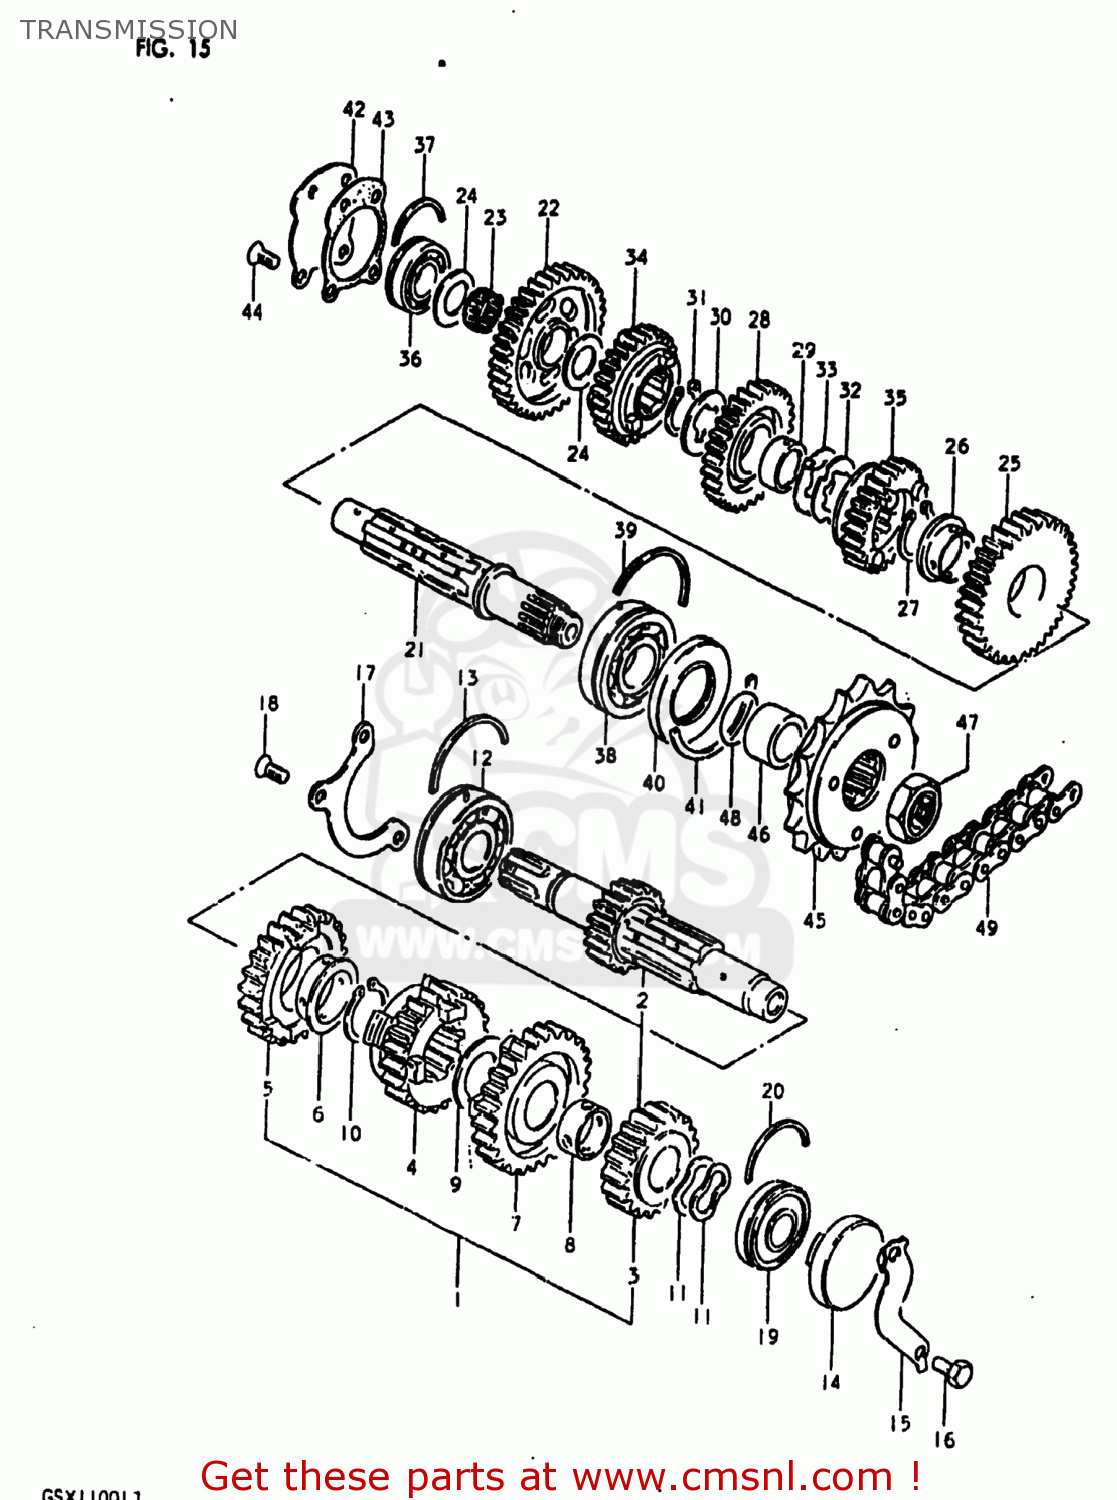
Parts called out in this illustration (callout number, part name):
1	SHAFT,COUNTER
2	SHAFT,COUNTER
3	GEAR,SECOND DRIVE
4	GEAR,3RD DRIVE(NT:21)
5	GEAR,FOURTH DRIVE
6	BUSH(28X32X2)
7	GEAR,FIFTH DRIVE
8	BUSHING
9	WASHER
10	CIRCLIP
11	WASHER
12	BEARING(25X62X17)
13	C-RING
14	PLUG
15	RETAINER,CL PUSH ROD OIL SEAL
16	BOLT
17	RETAINER,CNTR SHAFT BEARING
18	SCREW
19	BEARING(20X47X14)
20	C RING
21	SHAFT,DRIVE
22	GEAR,FIRST DRIVEN (NT:35)
23	BEARING(20X24X10).8
24	WASHER
25	GEAR,SECOND DRIVEN
26	BUSH(28X32X2)
27	CIRCLIP
28	GEAR,THIRD DRIVEN
29	BUSH,3RD DRIVEN GEAR
30	WASHER,LOCK
31	CIRCLIP
32	WASHER,LOCK
33	WASHER
34	GEAR,FOURTH DRIVEN
35	GEAR,FIFTH DRIVEN
36	BEARING
37	C RING
38	BEARING(25X62X17)
39	C-RING
40	SEAL,OIL(32X62X7)
41	C RING
42	PLATE,DRIVE SHAFT
43	GASKET,DRIVESHAFT PLATE (MCA)
44	SCREW
45	SPROCKET,ENGINE
46	SPACER(25X32X18.6)
47	NUT
48	O RING(D:1,ID:24.5)
49	CHAIN,DRIVE(DID630YL,96LE)
